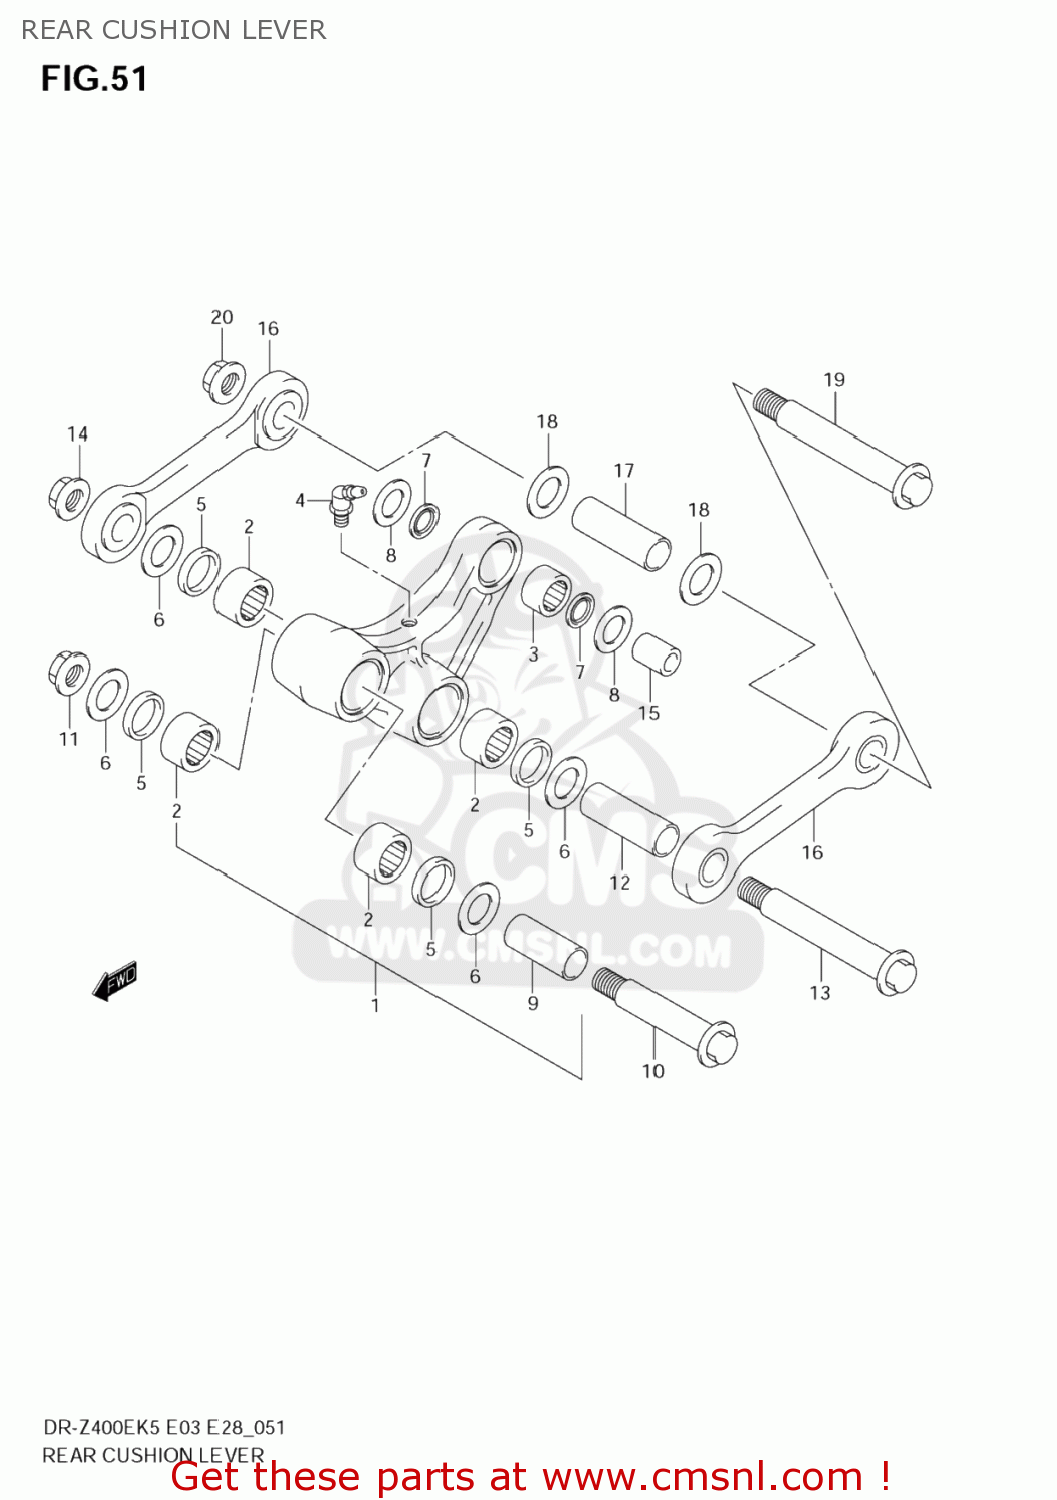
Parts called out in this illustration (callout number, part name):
1	LEVER SET,REAR CUSHION
2	BEARING(20X27X15)
3	BEARING(16X22X12)
4	NIPPLE,GREASE
5	SEAL,CUSHION LEVER DUST
6	WASHER,THRUST SWINGARM RR
7	SEAL,OIL(16X22X2.5)
8	WASHER,THRUST LVR CUSHION RR
9	SPACER,CUSHION LEVER FR
10	BOLT,RR CUSHION LEVER FR
11	NUT
12	SPACER,RR CUSHION
13	BOLT,RR CUSHION
14	NUT
15	SPACER,RR CUSHION LEVER RR
16	ROD SET,RR CUSHION
17	SPACER,RR CUSHION
18	WASHER,THRUST SWINGARM RR
19	BOLT,RR CUSHION
20	NUT
